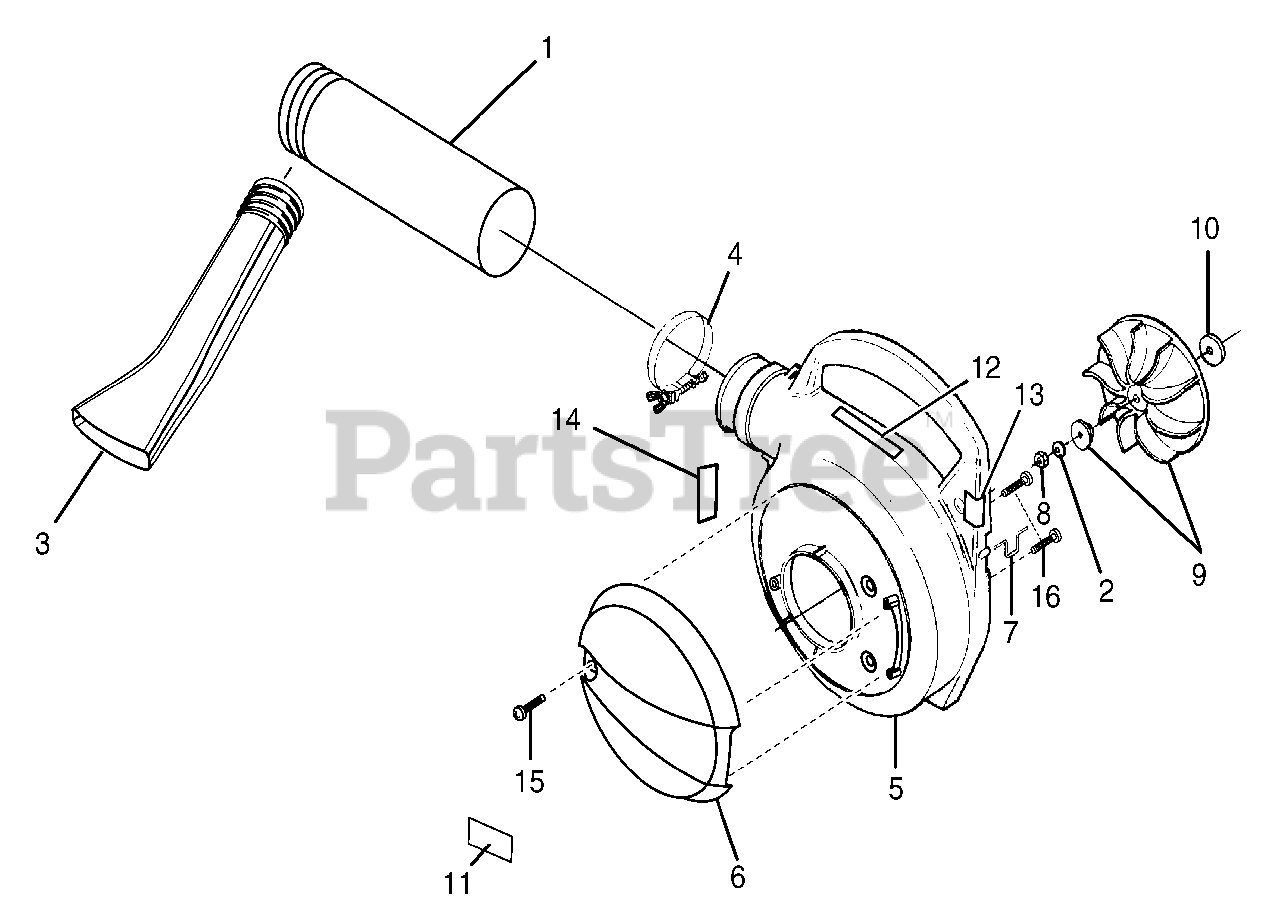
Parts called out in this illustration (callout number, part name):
1	UPPER TUBE
2	BELLVILLE WASHER (3/8 in.)
3	LOWER NOZZLE
4	CLAMP WITH FASTENERS
5	OUTER VOLUTE HOUSING
7	WIRE LOOP
8	HEX NUT (3/8-24)
9	BLOWER FAN KIT
10	FLAT WASHER
11	DOOR YARD BROOM DECAL
12	WARNING DECAL
13	OUTER VOLUTE DECAL
14	FAN INTAKE DECAL
15	SCREW (1/4-20)
16	SCREW (10-24 X 1/2 in TORX TRUSS HD)
